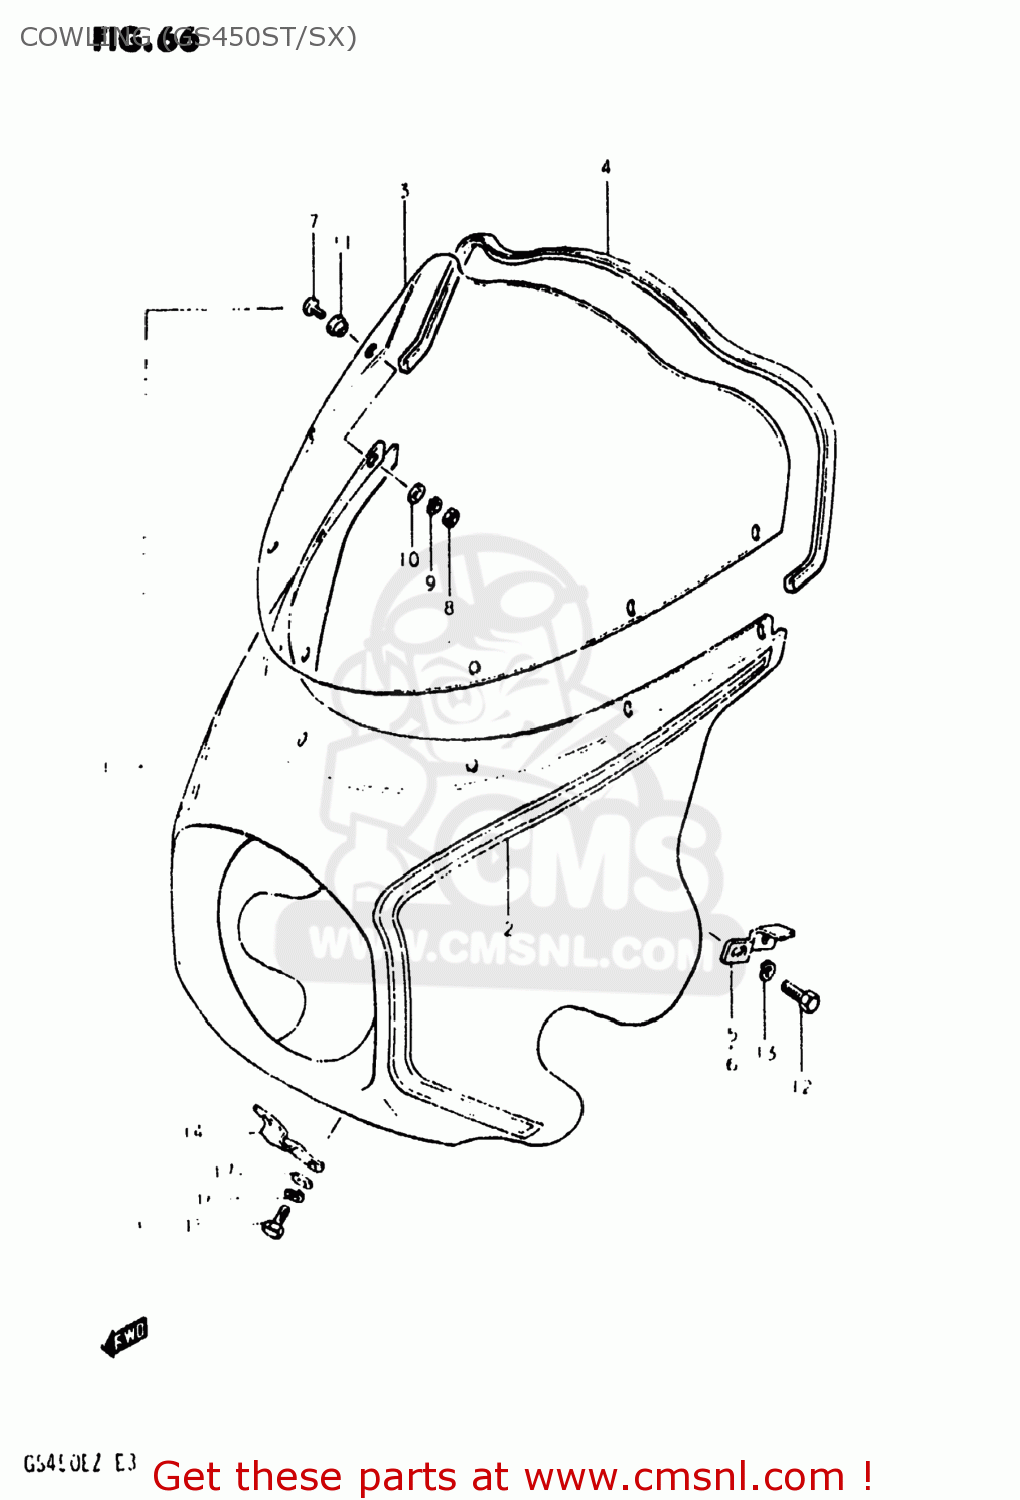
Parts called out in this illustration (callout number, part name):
1	COWLING ASSEMBLY
2	TAPE SET,COWLING
3	WINDOW,COWLING
4	MOLD,COWLING
5	BRACKET,COWLING,RIGHT
6	BRACKET, LH
7	SCREW M5X12 DIN 7985/N
8	NUT
9	LOCK WASHER
10	WASHER
11	CUSHION
12	BOLT
13	LOCK WASHER
14	BRACKET,COWLING,LOWER
15	BOLT
16	LOCK WASHER
17	WASHER
